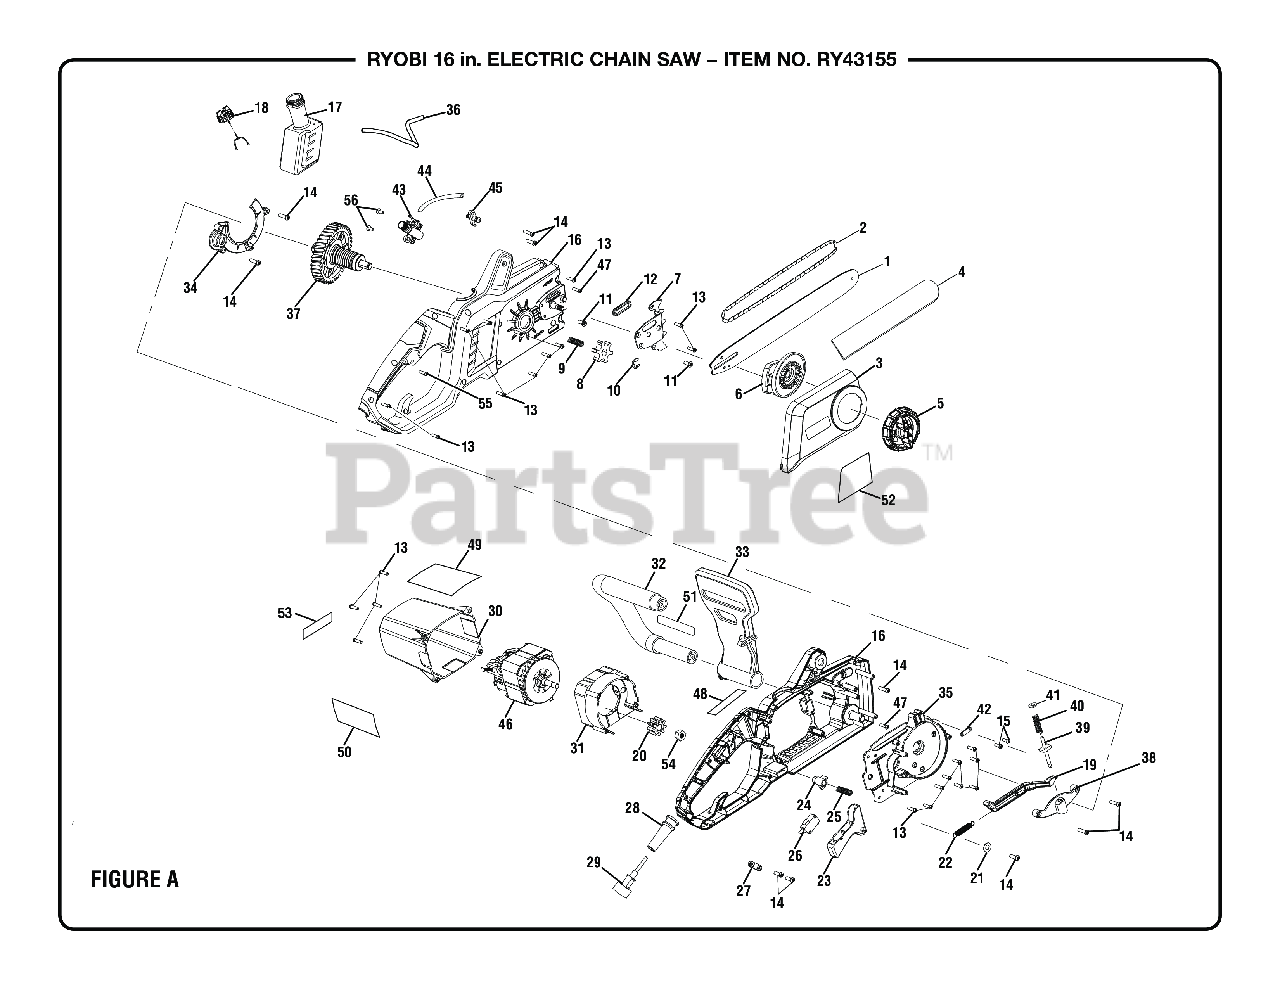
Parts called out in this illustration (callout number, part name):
3	Bar Cover Assembly (Inc. Key No. 52)
5	Chain Adjusting Knob Assembly
6	Chain Tensioner Assembly
7	Guide Plate w/Spike Bar
8	Chain Sprocket
9	Compression Spring
10	E-Clip (Retaining Ring)
11	Screw (M4 x 10 mm, Pan Hd.)
13	Screw (M4 x 16 mm, Pan Hd.)
14	Screw (M4 x 12 mm, Pan Hd.)
15	Screw (M3 x 8 mm, Pan Hd.)
16	Housing Assemblly (Inc. Key No. 48)
17	Oil Tank Assembly
18	Oil Tank Cap Assembly
22	Compression Spring
24	Lock-Off Button
25	Compression Spring
28	Bend Relief
30	Motor Cover (Inc. Key Nos. 49-50 & 53)
31	Front Motor Bracket
32	Front Handle
33	Front Handle Guard (Inc. Key No. 51)
34	Dust Shield
35	Motor Bracket
37	Output Shaft Gear Assembly
38	Brake Bar Plate
40	Compression Spring
42	Clamp (Brake Bar)
46	Motor Assembly
47	Screw (M5 x 20 mm, Pan Hd.)
48	Data Label
49	Danger/Warning Top Label
50	Warning Side Label
51	Warning Icons Label (FR/SP)
52	Logo Label
53	Logo Label
54	Flange Nut (M8)
55	Screw (M3 x 12 mm, Pan Hd.)
56	Screw (M3 x 8 mm, Pan Hd.)
